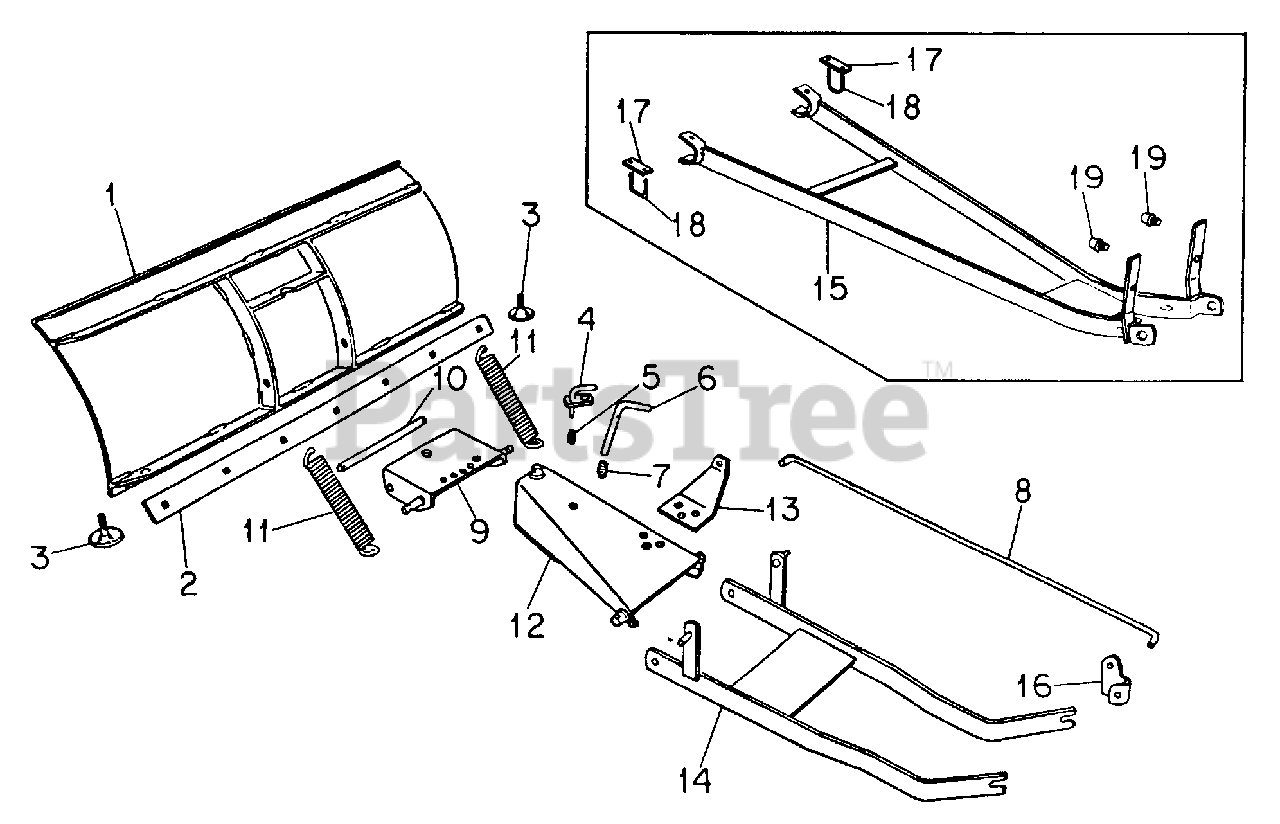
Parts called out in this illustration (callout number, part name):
1	BLADE ASSY -42 INCH-
2	EDGE, BLADE CUTTING -41 INCH-
3	SHOE ASSEMBLY, SKID
4	LOCK ASSEMBLY, SPRING TRIP
5	SPRING, COMPRESSION TYPE
6	PIN, ANGLING
7	SPRING, COMPRESSION TYPE
8	ROD, LIFT
9	FRAME ASSY, PIVOT
10	ROD, BLADE PIVOT
11	SPRING, EXTENSION TYPE
12	FRAME ASSY, MAIN
13	ARM, LIFT
14	FRAME, BLADE
15	FRAME, SUB
16	BRACKET, LIFT ROD
17	STRAP, REAR AXLE
18	U-BOLT, REAR AXLE
19	BUMPER, RUBBER
137218	PIN, 5/32 x 1-1/4 C-Z COTTER
137218	PIN, 13/32 x 1-1/4 C-Z COTTER
180175	SCREW, 1/2-13 x 1-1/4 C-Z HEX-HD CAP
